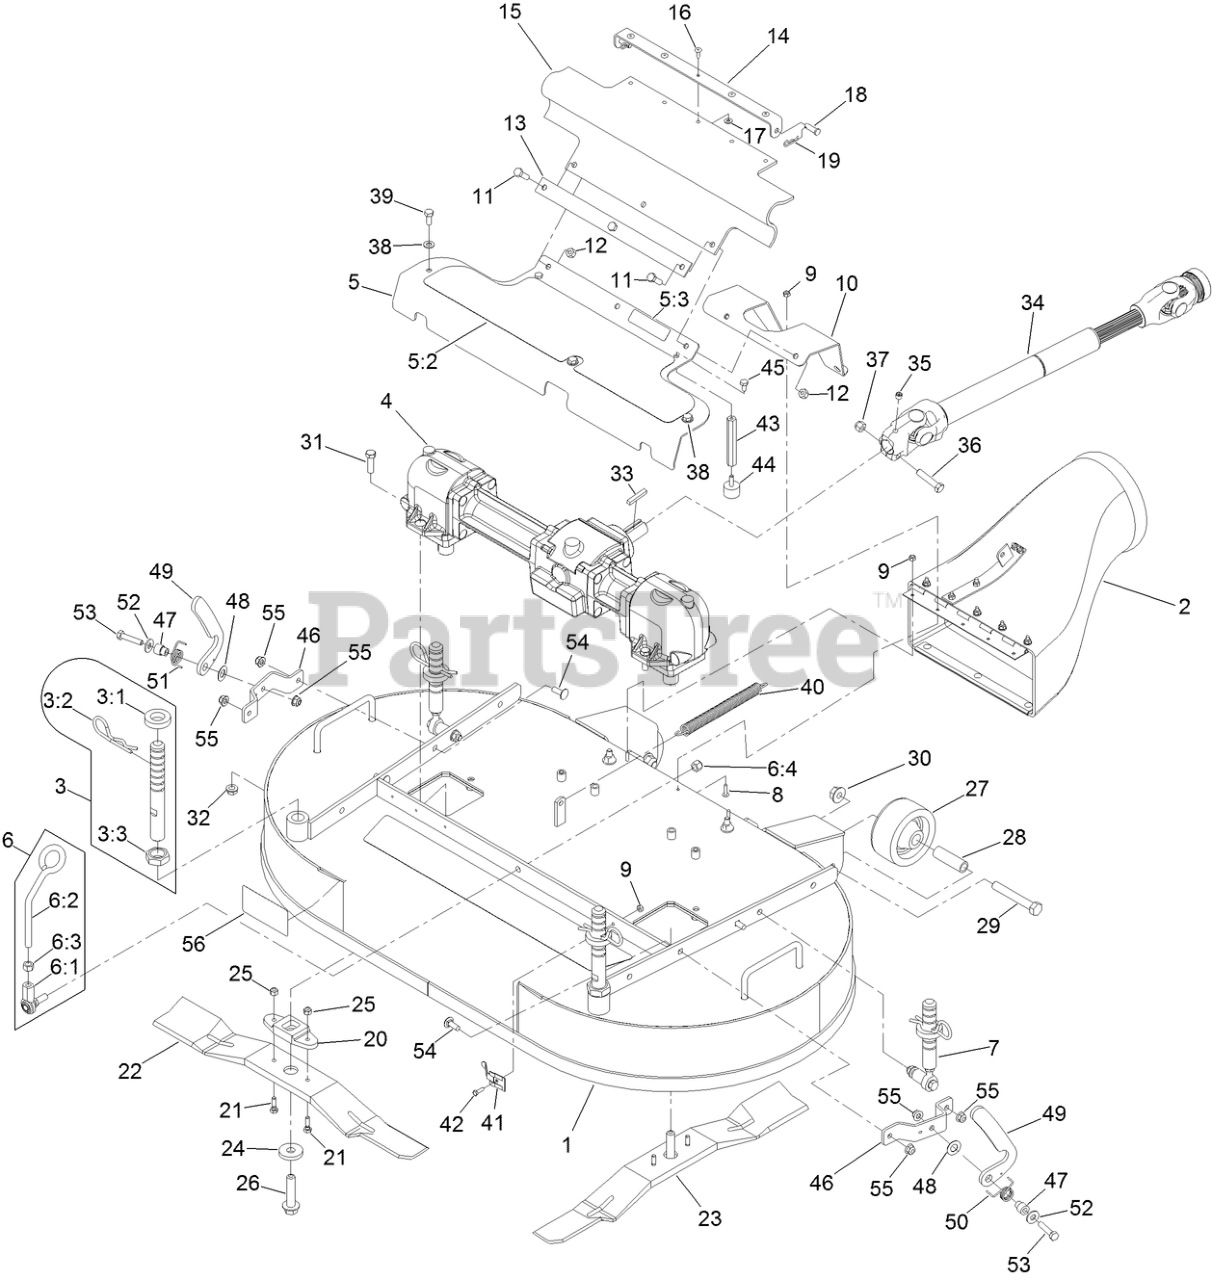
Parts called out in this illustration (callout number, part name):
1	DECK-CUTTING 42 W/DECALS
2	DISCHARGE TUBE ASM
3	FRONT DECK HEIGHT ADJUST ASM
3:1	SPACER-DECK SUPPORT
3:2	PIN-CUT HEIGHT
3:3	NUT-JAM
4	GEARBOX ASM
5	GEARBOX COVER ASM
5:2	PAD-ANTI SKID
5:3	DECAL-DANGER
6	DECK LATCH ASM
6:1	BALLJOINT-RH
6:2	LATCH-DECK
6:3	NUT-HEX
6:4	NUT-LOCK
7	REAR DECK HEIGHT ADJUST ASM
8	SCREW-HEAD, TRUSS
9	NUT-LOCK, NI
10	GUARD-DRIVE SHAFT
11	SCREW-HH
12	NUT-LOCK, NI
13	STRAP-DRIVE, LINE COVER
14	BRACKET-GUARD, PTO
15	GUARD-PTO
16	RIVET-BLIND
17	WASHER-FLAT
18	PIN-CLEVIS
19	PIN-COTTER
20	DRIVER-BLADE
21	BOLT-SHEAR
22	BLADE-22IN, RH
23	BLADE-22IN, LH
24	WASHER
25	NUT-LOCK, NI
26	BOLT-BLADE
27	ROLLER-DECK
28	SPACER-ROLLER
29	SCREW-HH
30	NUT-HHF
31	SCREW-HH
32	NUT-HHF, WHIZ
33	KEY-SQUARE
34	DRIVE SHAFT ASM
35	SCREW-SET, HSH
36	SCREW-HH
37	NUT-LOCK, NI
38	WASHER-PLAIN
39	SCREW-HH
40	SPRING-EXTENSION
41	CLIP-DECK, HOLD UP ROD
43	STAND-OFF
44	BUMPER
45	SCREW-HH
46	BRACKET-LATCH PIVOT
47	COLLAR-BASKET
48	WASHER-PLASTIC
49	LATCH - DECK
50	SPRING-TORSION, LH (YELLOW)
51	SPRING-TORSION, RH
52	WASHER-FLAT
53	SCREW-HH
54	BOLT-CARR
55	NUT-HF, NI
